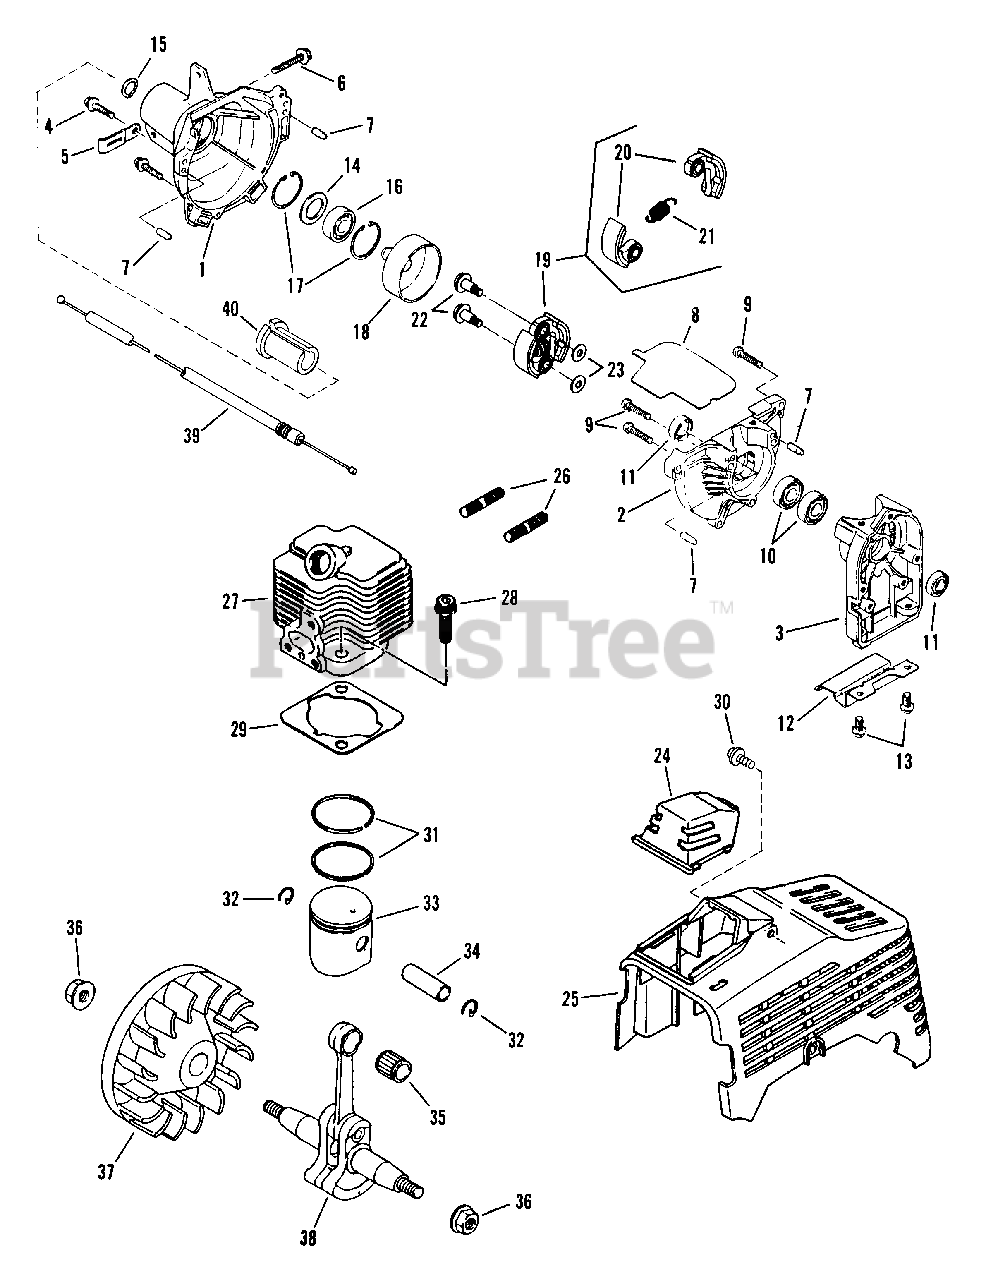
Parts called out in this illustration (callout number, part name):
1	CASE, Clutch
2	CASE, Drive
3	CASE, Starter
4	BOLT/WASHER
6	BOLT/WASHER
7	PIN, Dowel
8	GASKET, Muffler/Tank
9	SCREW, Cross Pan Head
10	BEARING, Ball
11	SEAL, Oil
13	SCREW/WASHER
15	RING, Snap
16	BEARING, Ball
17	RING, Snap
18	DRUM, Clutch
19	ASSEMBLY, Clutch
20	FLYWHEEL
22	BOLT, Clutch
24	GUARD, Spark Plug
25	COVER, Top
26	BOLT, Stud
27	CYLINDER
28	BOLT, Flange
29	GASKET, Cylinder
30	SCREW/WASHER
31	RING, Top
32	CLIP, Piston Pin
33	ASSEMBLY, Piston
34	PIN, Piston
35	BEARING, Needle
36	NUT, Conical Spring
38	ASSEMBLY, Crank Shaft
39	CABLE, Throttle
40	ISO-Mount
